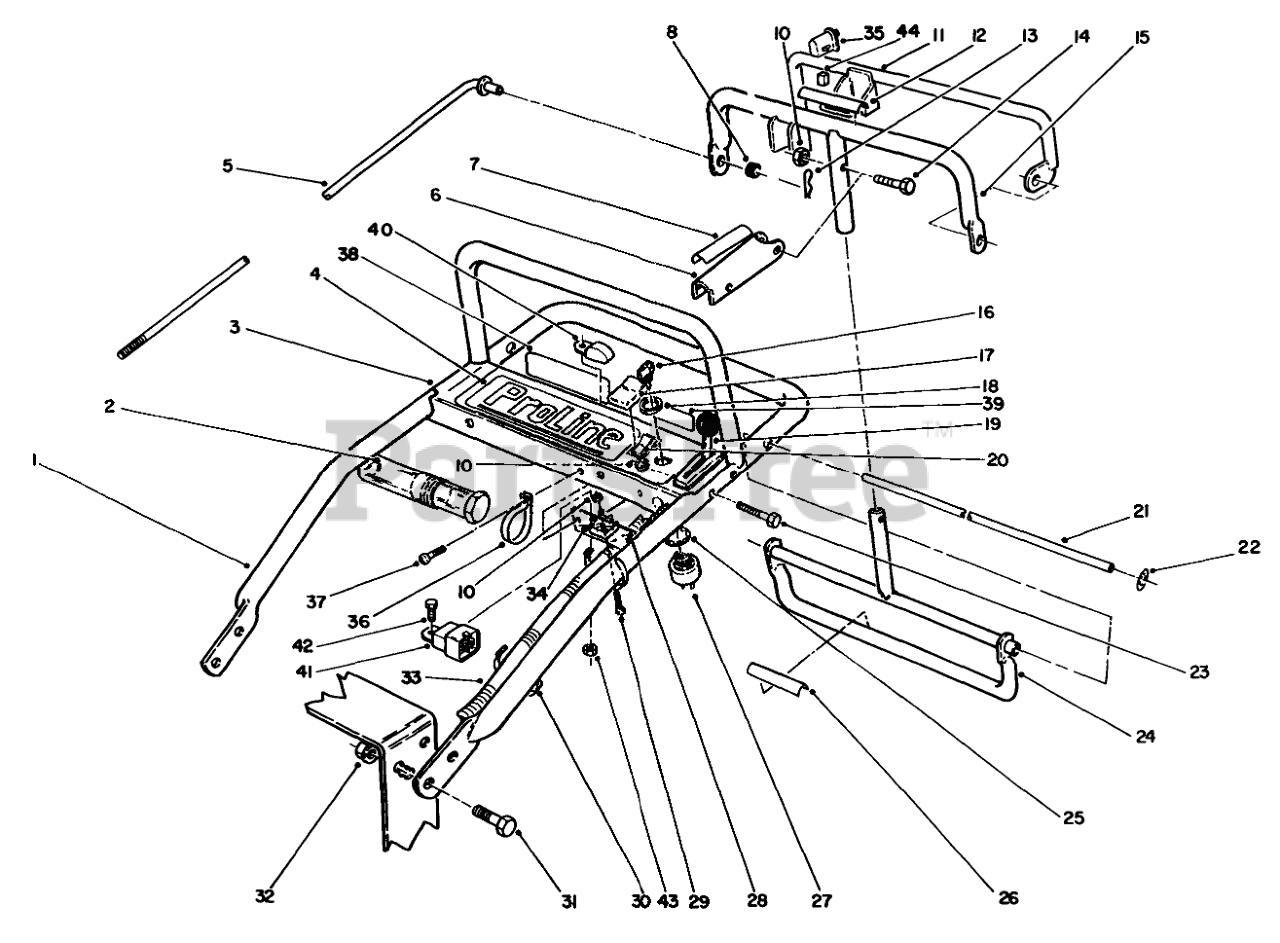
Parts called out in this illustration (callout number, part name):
1	Handle-Upper
2	TUBE-MANUAL
3	Panel-Control
4	DECAL-CONTROL PANEL
5	ROD-CONTROL
6	Lever-Parking Brake
7	DECAL-LEVER, PARKING
8	GROMMET-RUBBER
10	NUT-LOCK, NI
11	Bail
12	DECAL
13	PIN-COTTER
14	SCREW-SHH
15	Bar
16	KEY-IGNITION
17	BOOT-SWITCH
18	NUT-HH
19	CONTROL-THROTTLE
20	SWITCH
21	PIVOT ROD
22	NUT-PUSH-ON, CIRCULAR
23	SCREW-SHH
24	Control Pivot
25	WASHER-TOOTH, INTERNAL
26	DECAL
27	Switch-Off/On (Incl. Ref. #16, 18, & 25)
28	Panel-Bottom
29	SCREW-HWH
30	TIE-CABLE
31	SCREW-HHF
32	NUT-HF
33	Wire Harness (Ref.)
34	RECTIFIER-BRIDGE
35	SWITCH-BAIL
36	CLAMP-R
37	SCREW-HWHTF
38	DECAL-INSTRUCTION
39	DECAL-INSTRUCTION, SAFETY
40	Module
41	RELAY
42	SCREW-HH
43	NUT-LOCK, NI
44	CONNECTOR-BODY
